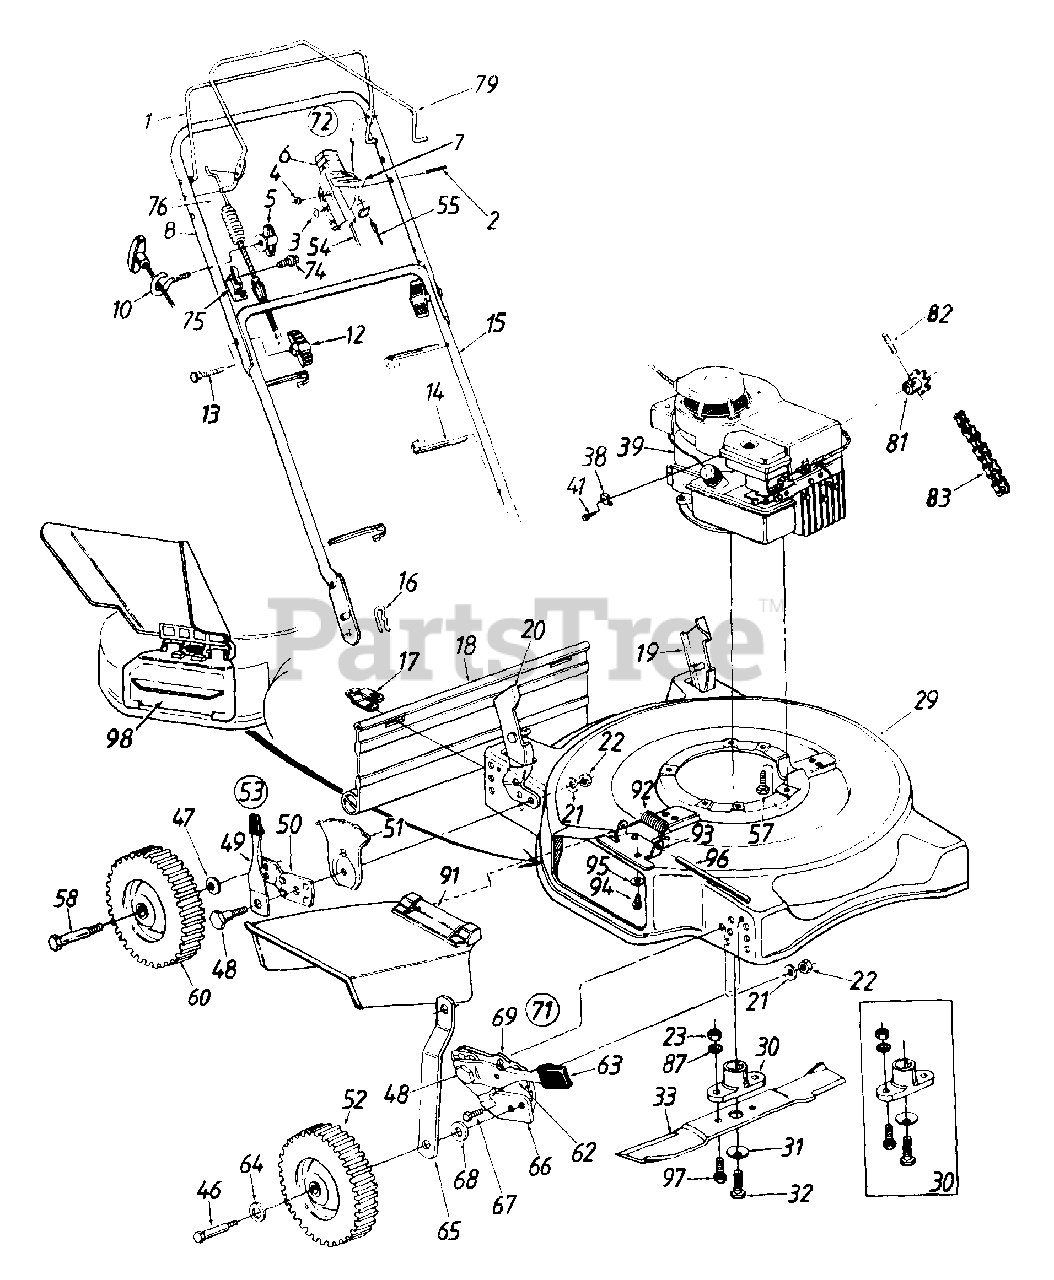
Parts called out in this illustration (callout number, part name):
2	Oval C-Sunk Mach. Scr.
3	Spr. Wash..66" I.D.
4	Hex L-Nut 1/4-20 Thd.
5	Wing Nut 1/4-20 Thd.
6	Throttle Body
7	Throttle Lever
12	Hand Knob
13	Curved Hd. Bolt 5/16-18 x 2" Lg.
14	Cable Tie
16	Hairpin Cotter
17	Hinge Clip
18	Rear Flap
22	Hex Nut 3/8-16 Thd.
23	Hex Nut 3/8-24 Thd.
29	22" Deck Ass'y.
30	Blade Adapter Kit
31	Bell-Wash..39" I.D.
32	Hex Bolt 3/8-24 x 1.5" Lg.
33	22" Blade
38	Cable Clamp (B&S)
39	Engine
41	Hex Wash. Hd. Scr. #10-32 x .62" Lg. (B&S)
46	Front Axle Bolt
47	Bell-Wash..400" I.D. x .88"
48	Shld. Bolt .50" Dia. x .357"
49	Spring Lever Ass'y. w/Knob
51	Height Adj. Plate
52	Front Wheel Ass'y. Comp.
53	Height Adj. Ass'y. Comp.- R.H.
54	Throttle Control Wire - 51" (B&S)
55	Control Cable - 39" (B&S)
57	Hex L-Wash. Hd. Scr. 3/8-16 x 1.0" Lg.
58	Rear Axle Bolt
60	Rear Wheel Ass'y. Comp.
62	Spring Lever
63	Spring Lever Knob
64	Fl-Wash..531" I.D. x .93"
67	Hex AB-Tap 1/4-.62" Lg.
68	Bell-Wash..380" I.D. x .88"
69	Index Plate
71	Front Height Adj. Ass'y.- R.H.
72	Throttle Box Comp.
74	Hex Wash. AB-Tap Scr. 5/16 x .75" Lg.
75	Cable Brkt.
76	Clutch Cable w/Spring - 47"
82	Spring Pin Spir. 3/16" Dia. x 1" Lg.
83	#48 Chain 1/2" Pitch 50 Links (Endless)
87	L-Wash. 3/8" I.D.
91	Chute Deflector Ass'y.
92	Torsion Spring
93	Adapter Plate
94	Hex Self-Tap Scr. 1/4-20 x .5" Lg.
95	Bell-Wash. 1/4" I.D.
96	Hinge Pin
97	Hex Bolt 3/8-24 x 1" Lg.
98	Mulching Plug
